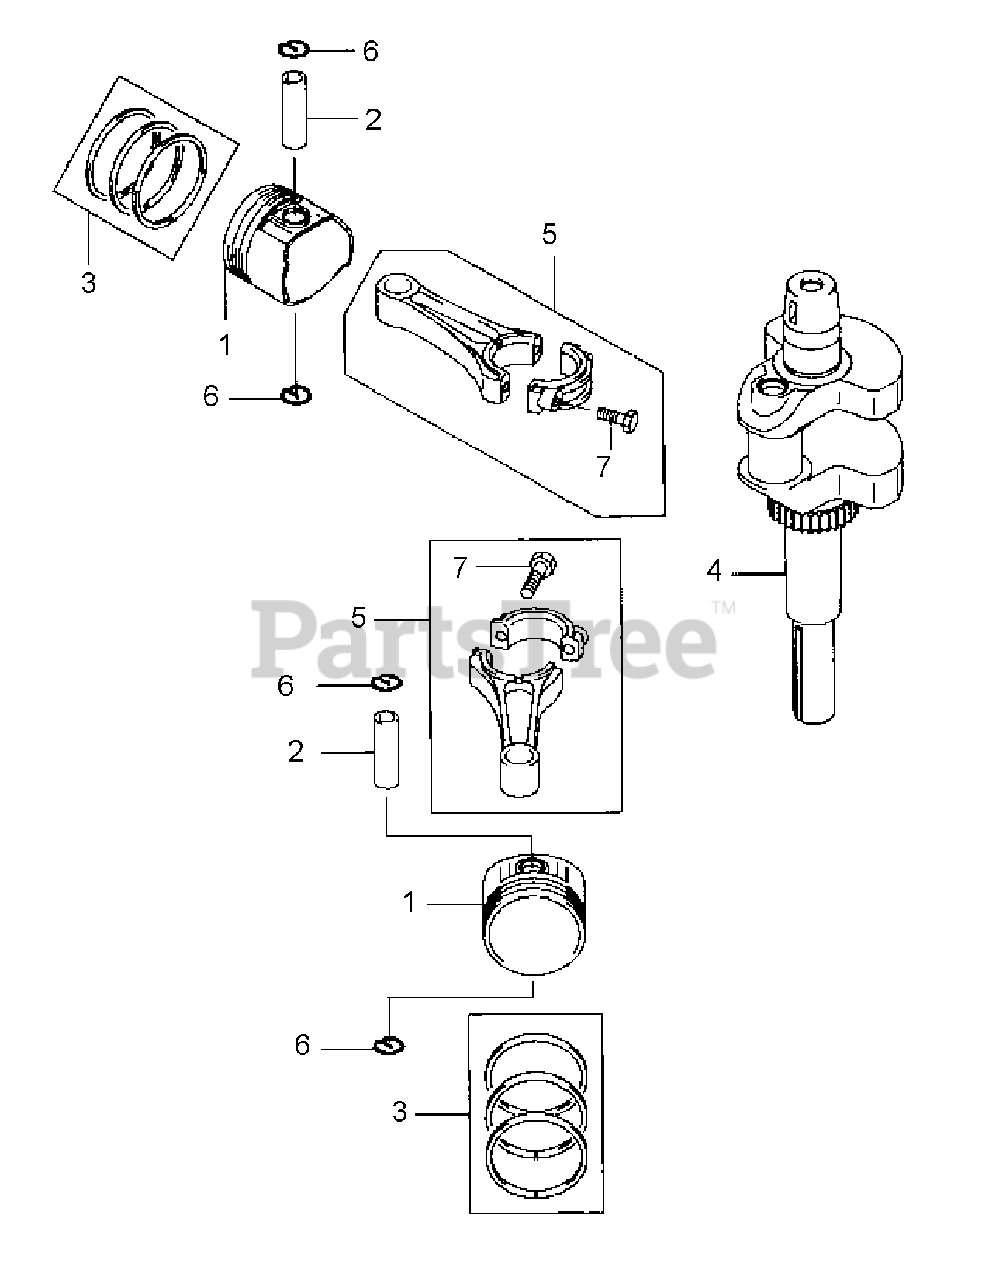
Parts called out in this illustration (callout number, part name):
1	PISTON-ENGINE
1	PISTON-ENGINE L, 0.50
3	RING-SET-PISTON
3	RING-SET-PISTON L, 0.50
4	CRANKSHAFT-COMP
5	ROD-ASSY-CONNECTING
5	ROD-ASSY-CONNECTING, U/S=.50
7	BOLT-FLANGED
